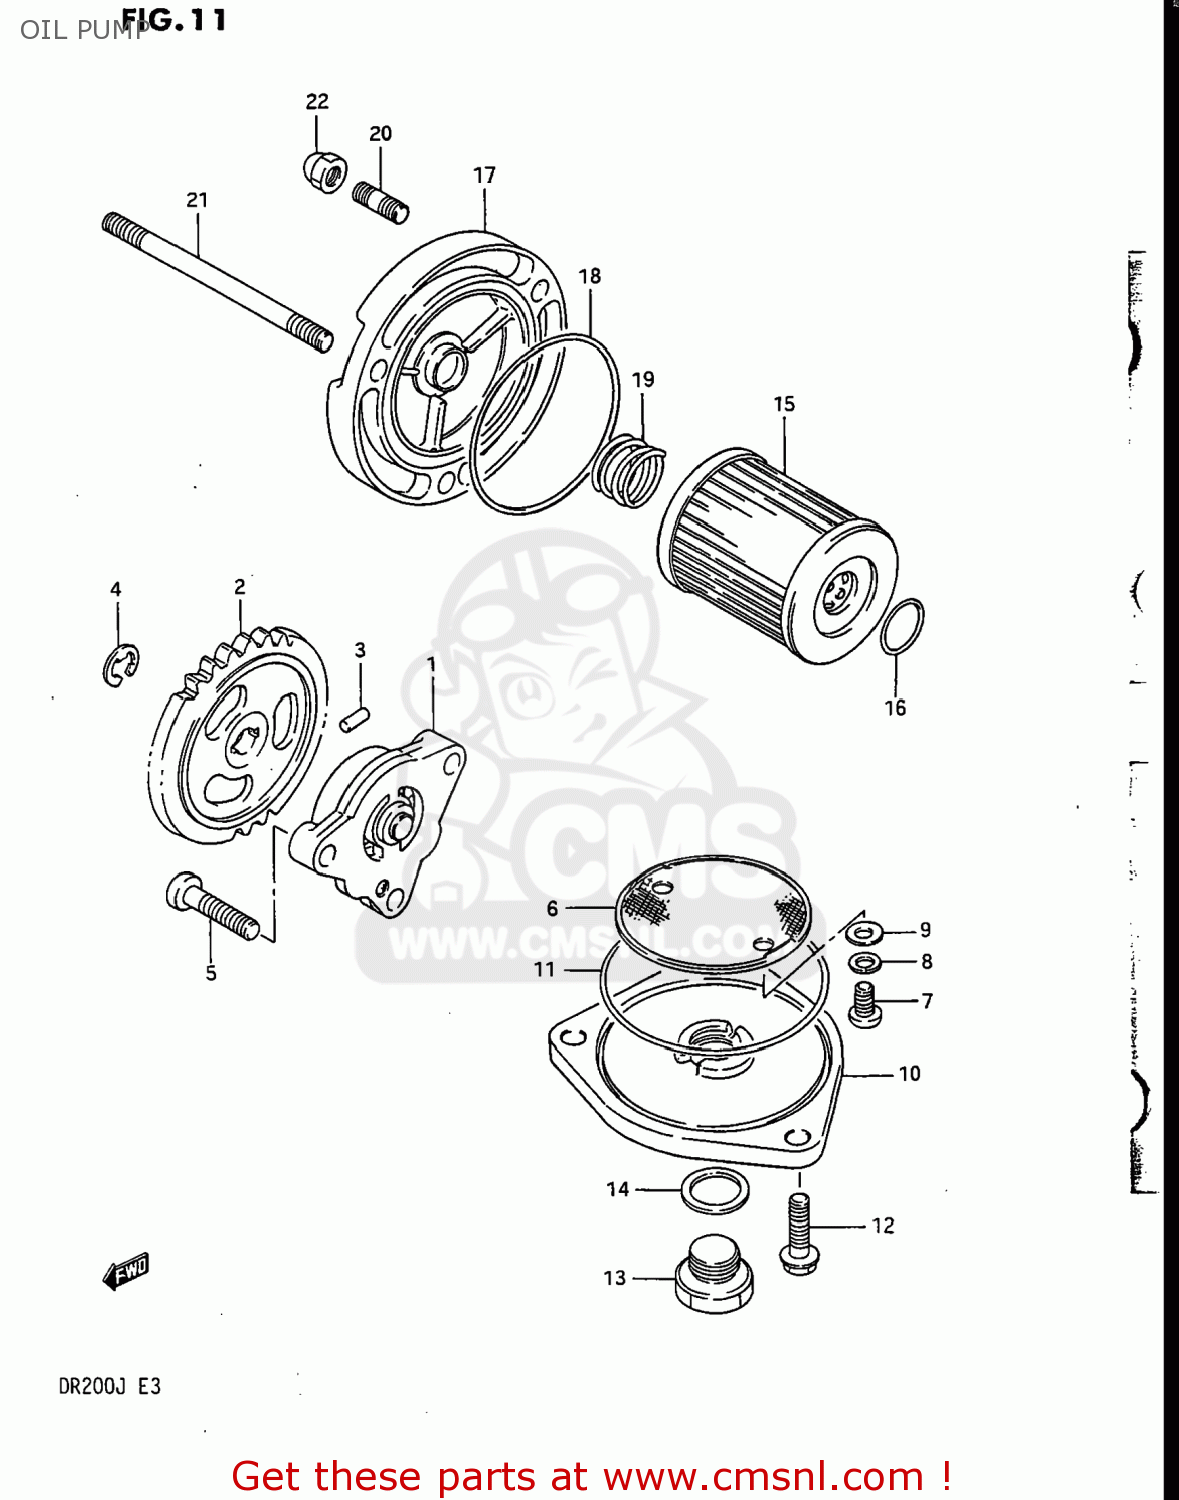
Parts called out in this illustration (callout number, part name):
1	PUMP ASSY,ENGINE OIL
2	GEAR,OIL PUMP DRIVEN (N
3	PIN(2.5X11.8)
4	E RING 6MM
5	SCREW
6	STRAINER,ENGINE OIL
7	SCREW 5X12
8	LOCK WASHER
9	WASHER
10	CAP,OIL STRAINER
11	O RING(D:2.4,ID:60.5)
12	BOLT
13	PLUG
14	GASKET(14X19.2X2) (NAS)
15	FILTER,OIL
16	O RING(D:1.9,ID:13)
17	CAP,OIL FILTER
18	O RING(D:2.4,ID:52.6)
19	SPRING
20	STUD 6X12
21	STUD BOLT
22	NUT 6MM
